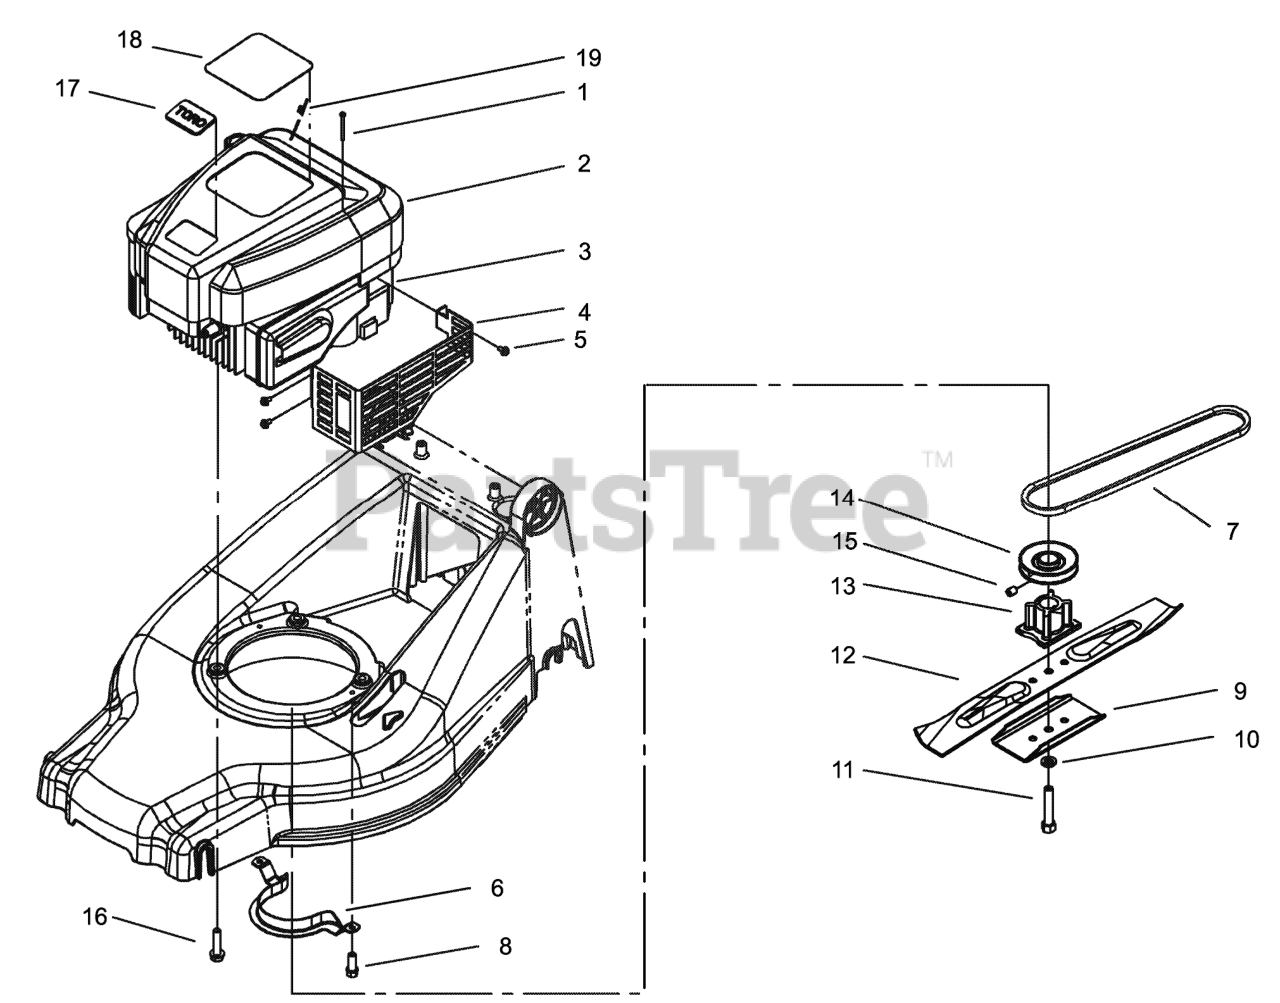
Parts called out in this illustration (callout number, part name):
1	SCREW-PPH
2	SHROUD-ENGINE
4	SHIELD-MUFFLER
5	SCREW-HWH
6	GUIDE-BELT, ENGINE
7	V-BELT
8	SCREW-HWH
9	STIFFENER-BLADE
10	WASHER-LOCK
11	BOLT-BLADE
13	RETAINER-BLADE
14	PULLEY ASM
15	SCREW-SET
16	SCREW-HWH
17	PLATE-LOGO
18	DECAL-ENGINE
19	STOP-ROPE
